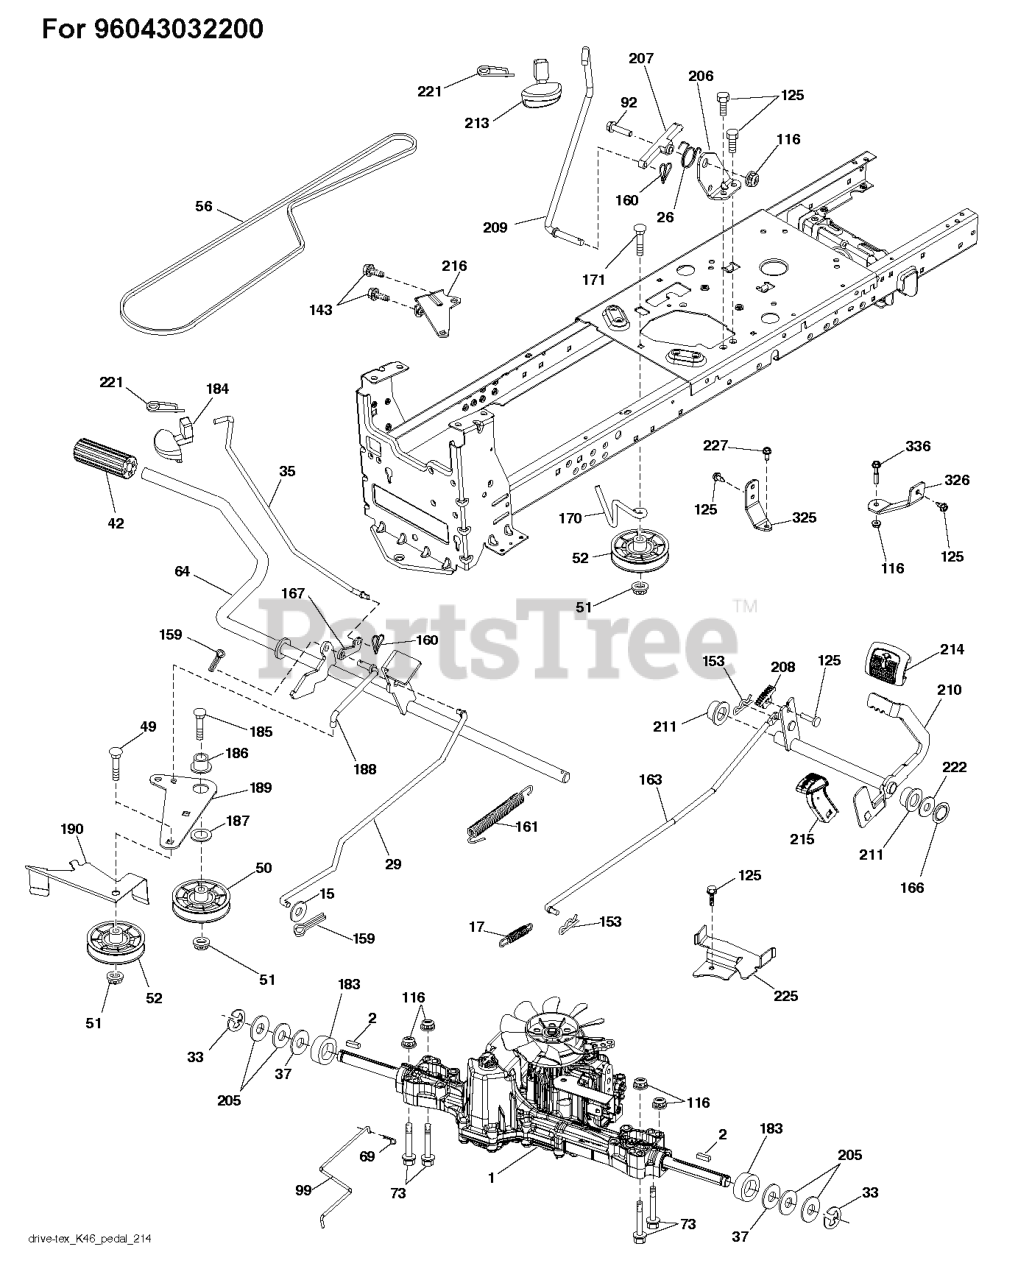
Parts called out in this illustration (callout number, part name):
2	SQUARE KEY
15	WASHER PLAIN WASHER 3/8 X 0.08
15	WASHER
17	SPRING.BRAKE.K46.GREEN
26	SPRING.RETURN.CRUISE
29	ROD.BRAKE.K46
35	ROD ROD.PARKINGBRAKE.GT.HUSQ/P
37	WASHER.HARDENED
42	PEDAL COVER
50	IDLER.FLAT.910.OFFSET
51	NUT LOCK FLG 3/8-16 UNC
52	IDLER.V-GROOVE.910.OFFSET
64	SHAFT.ASM.PEDAL.BRK.CNTR
69	HAIRPIN.SOFT.ZINC.059X1.125
99	ARM.PIVOTING.TCRD.GEN2.5.BAGGE
125	SCREW
153	RETAINER M
160	GSPW Retainers
161	SPRING, RETURN LT
166	NUT.PUSH.625
167	LATCH.BRAKE.SPRING
170	KEEPER.V-IDLER.CENTER.
183	SPACER AXLE
184	HANDLE.PARKING.BRAKE.H (BLK)
186	SPACER.RETAINER
188	LINK.CLUTCH.GROUND DRIVE.LONG
189	BELLCRANK.GROUND.DRIVE.TEX.
190	KEEPER.BELLCRANK.DRIVE
206	BRACKET.MOUNT.CRUISE.LATCH
209	ROD ROD.CRUISECONTROL.GT.HUSQ/
210	ROCKER.ASM.PEDAL.CONTR
211	BEARING.NYLON
213	KNOB.CONTROL.CRUSIE.HU
214	PEDAL.FORWARD.PAD.TEX
215	PEDAL.COVER.REVERSE.CRD.X428BK
216	BRACKET.PULLEY.IDLER.W/TEX
221	RETAINER.SPRING.CLIP.H
222	WASHER 21/32 X 1-1/4 X 10 GA.
225	KEEPER.BELT.TRANSAXLE.K46
325	BRACKET.TRQ.STP.46.20".TIRE.LH
326	BRCKT.PNT.TRQ.STP.46.20TIRE.RH
